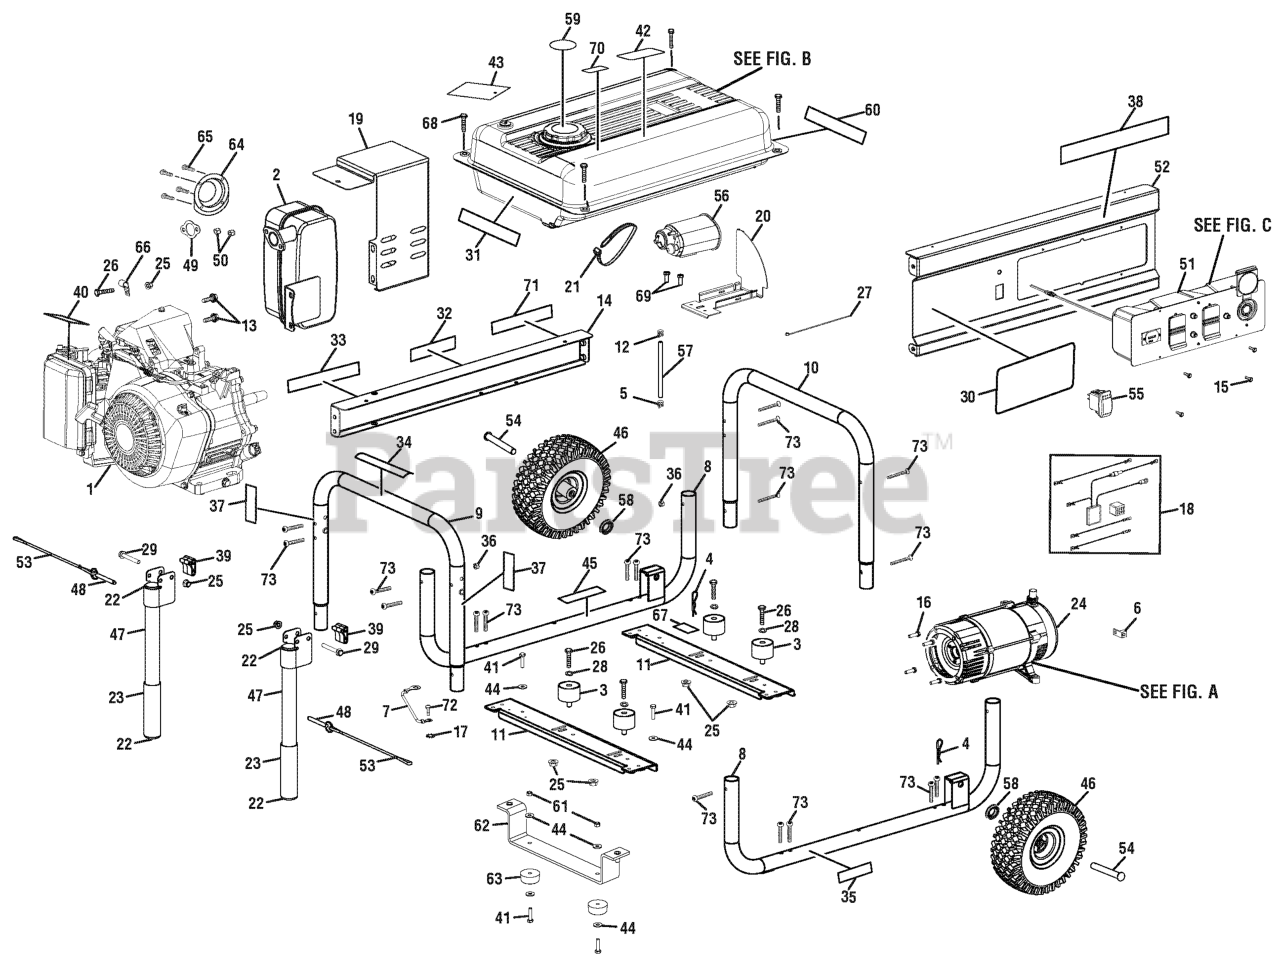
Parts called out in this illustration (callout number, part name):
1	Engine (Subaru)(Parts available at your local Subaru dealer)
2	MUFFLER (SUBARU EX30)
3	ISOLATOR
4	HITCH PIN
5	CLAMP (3/8 IN.)
6	GROUND LUG
7	GROUND WIRE ASSEMBLY
8	LOWER FRAME ASSEMBLY
9	TUBE ASSEMBLY (LEFT)
10	TUBE ASSEMBLY (RIGHT)
11	CROSS BRACE
12	FUEL LINE CLAMP (1/2 IN.)
13	BOLT (5/16-24 X 5/8 IN.)
14	BACK PANEL
15	SCREW (6-20 X 3/8 IN.)
16	BOLT (3/8-16 X 1.25 IN.)
17	STAR WASHER (M8)
18	WIRE HARNESS
19	BACK MUFFLER COVER
20	BRACKET (CARBON CANISTER)
21	CABLE TIE
22	END CAP
23	HANDLE GRIP
24	GENERATOR HEAD W/AVR
25	NUT (M8)
26	BOLT (M8 X 35 MM, HEX HD.)
27	TIE WRAP
28	WASHER (M8)
29	BOLT (M8 X 55 MM, HEX HD.)
30	LOGO LABEL
31	ELECTRIC START LABEL
32	HOT SURFACE LABEL
33	DANGER LABEL
34	FIRE DANGER LABEL
35	ENGINE LUBRICANT LABEL
36	NUT (M6)
37	LOCKING PIN LABEL
38	SUBARU LABEL
39	HANDLE BRACKET SPACER
40	CHOKE LABEL
41	BOLT (M6 X 1 IN., HEX HD.)
42	CPSC LABEL
43	HANGTAG (ENGINE WARNING)
44	WASHER (ID6.4 X OD17 X 1.6T)
45	COMBUSTION WARNING LABEL
46	WHEEL ASSEMBLY
47	HANDLE ASSEMBLY
48	RELEASE PIN (5/16 X 2 IN.)
49	MUFFLER GASKET
50	NUT( M8)
51	PANEL ASSEMBLY
52	FRONT PANEL
53	LANYARD (3/16 IN.)
55	STOP SWITCH W/LOCK
56	CANISTER
57	PURGE HOSE
58	WASHER (1/2 IN.)
59	FUEL STABILIZER LABEL
60	GROUND WARNING LABEL
61	NUT (M6)
62	FOOT BRACKET
63	RUBBER FOOT
64	SPARK ARRESTOR
65	SCREW (8-32 X 3/8 IN.)
66	J-CLAMP
67	GROUND LABEL
68	SCREW (1/4-14 X 1.25 IN.)
69	SCREW (#10-16 X 3/4 IN.)
70	E85 LABEL
71	FIRE DISTANCE LABEL
72	SCREW (M6 X 16 MM, HEX HD.)
73	SCREW (M6 X 50 MM, T30, PANHD)
